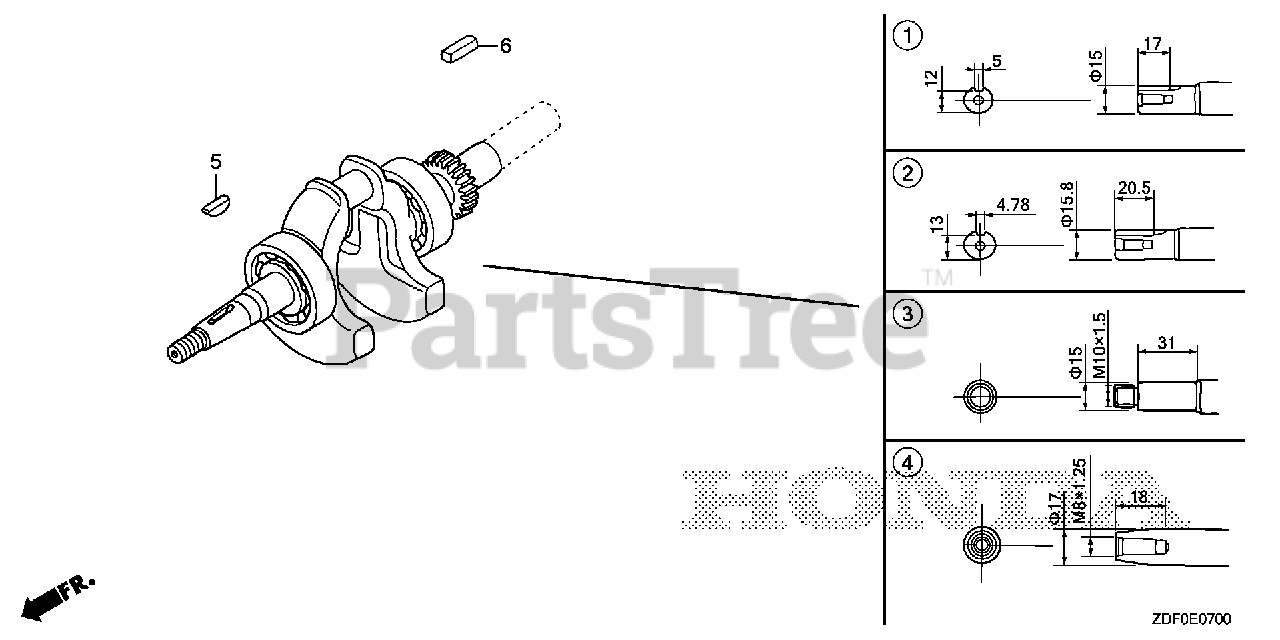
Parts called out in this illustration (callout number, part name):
2	CRANKSHAFT
5	KEY, SPECIAL
6	KEY (4.78MM)
